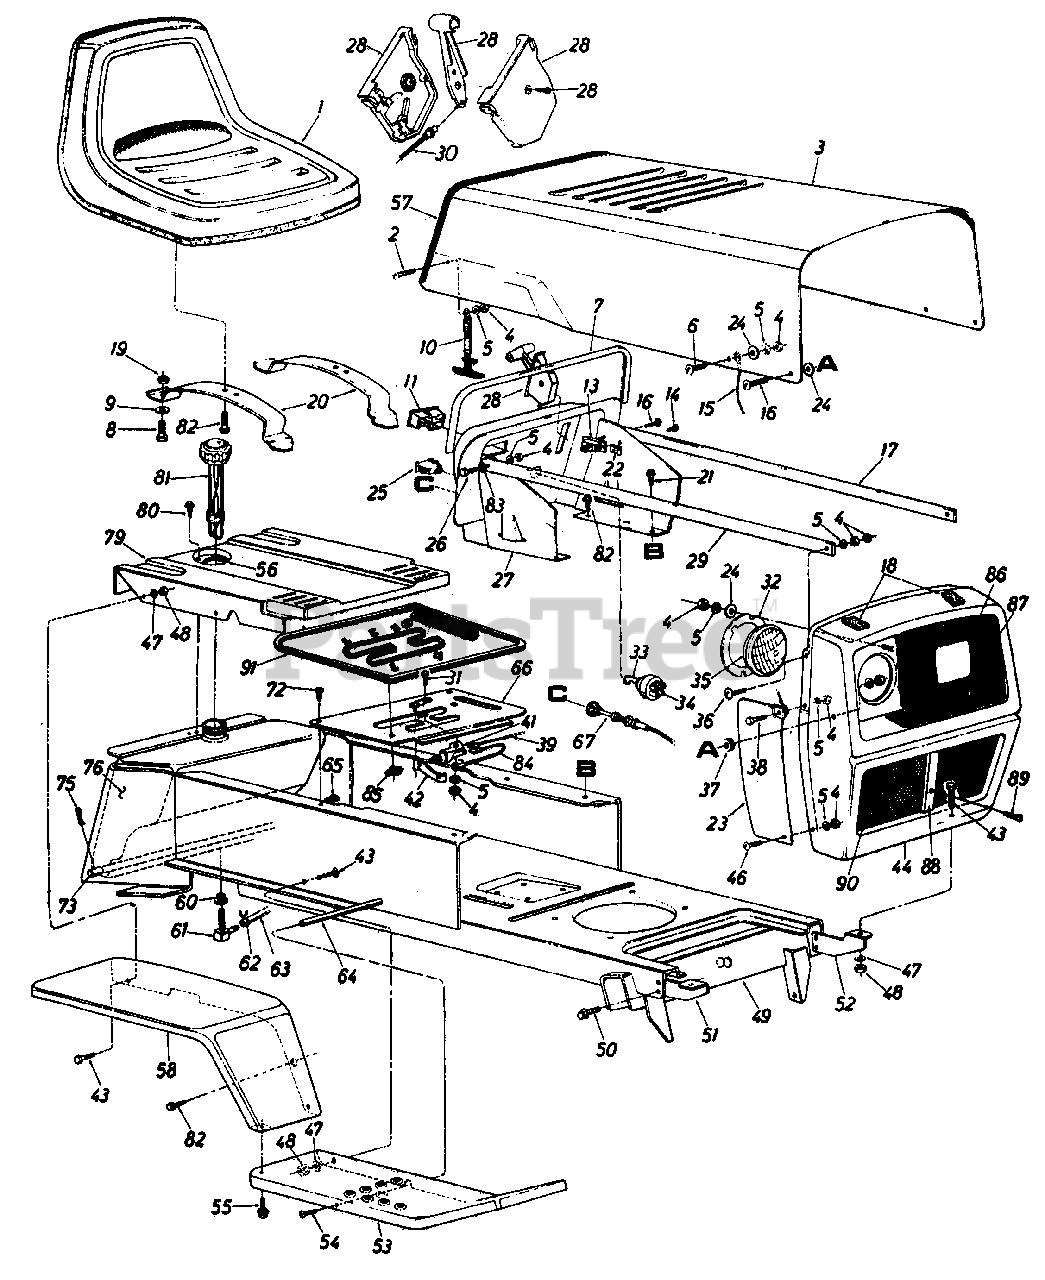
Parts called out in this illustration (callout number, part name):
1	Seat Assembly
2	Truss Mach. Scr. 1/4-20 x .50" Lg.*
5	L-Wash. 1/4" Scr.*
6	Truss Mach. Scr. 1/4-20 x .50" Lg.*
7	Vinyl Molding Strip 29"
8	Hex Nylon Scr. 1/2-13 x .75" Lg
9	Fl-Wash 501 I.D. x 1.00" O.D. x .090
10	Hood Latch Ass'y.
11	Ammeter
13	Circuit Breaker 8 Amp.
14	Hex Tap Scr. #10 x .50" Lg.*
16	Truss Mach. Scr. 1/4-20 x .75" Lg.*
17	Grille Positioning Rod
18	PVC Foam Strip 1/2 x 1.00" x 2.00" Lg.
19	Hex Nut 1/2-13 Thd.*
22	Speed Nut #10Z
23	Grille Side Panel R.H.
24	Fl-Wash. 1/4" I.D.
25	Light Switch
26	Truss Hd. Scr. 1/4-20 x 1.00" Lg.*
27	Dash Panel Assy
28	Throttle Control Box Comp.
29	Grille Positioning Rod
30	Trottle Control Cable
31	Hex Bolt 1/4-20 x .50" Lg.*
32	Head Lamp Retainer
33	Ignition Key
34	Ignition Switch
35	Head Lamp
36	Truss Machine Scr. 1/4-20 x .75" Lg.*
37	Rubber Wash. .50" I.D. x 1.00 O.D. x .25 Thk.
38	Truss Mach. Scr. 1/4-20 x .50" Lg.*
39	Reverse Lockout Wire Harness
41	Safety Switch
42	Switch Actuator Spring
43	Hex Scr. 5/16-18 x .75" Lg.*
44	Grille Ass'y.
46	Truss Mach. Scr. 1/4-20 x .50" Lg.*
47	L-Wash. 5/16" Scr.*
48	Hex Nut 5/16-18 Thd.*
49	Lower Frame Ass'y.
50	Hex Thd. Rolling Scr. 5/16" x.75" Lg.
51	Grille Mount Brkt. R.H.
52	Grille Mount Brkt. L.H.
53	Running Board R.H.
54	Truss Mach. Scr. 5/16-18 x .75" Lg.*
55	Hex Thd. Rolling Scr. 5/16-24 x .75" Lg.
56	Grommet
57	Vinyl Moulding Strip 30"
58	Fender Ass'y. R.H.
60	Bushing
61	90ø Nipple
62	Hose Clamp 3/8"
63	Gas Line 46" Lg.
64	Running Board Rod
65	Speed Nut #10-24
66	Transmission Cover Ass'y.
67	Choke Control Comp.
72	Truss Hd. Scr. #10 x .50" Lg.
75	Internal Cotter Pin
79	Seat Plate
80	Hex Thd. Rolling Scr. 5/16-24 x.75" Lg.
81	Gas Gauge
82	Hex Thd. Rolling Scr. 5/16-24 x.75" Lg.
83	External Wash. 1/4" I.D.
84	Electric Wire
85	Speed Nut 1/4" Stud
86	Headlight Bezel
87	Hex Wash. Hd. F-Tap Scr. #8-32 x .38" Lg.
88	Center Moulding
89	Truss Mach. Scr. #10-24 x .62" Lg.
90	Grille Screen
91	Transmission Cover
